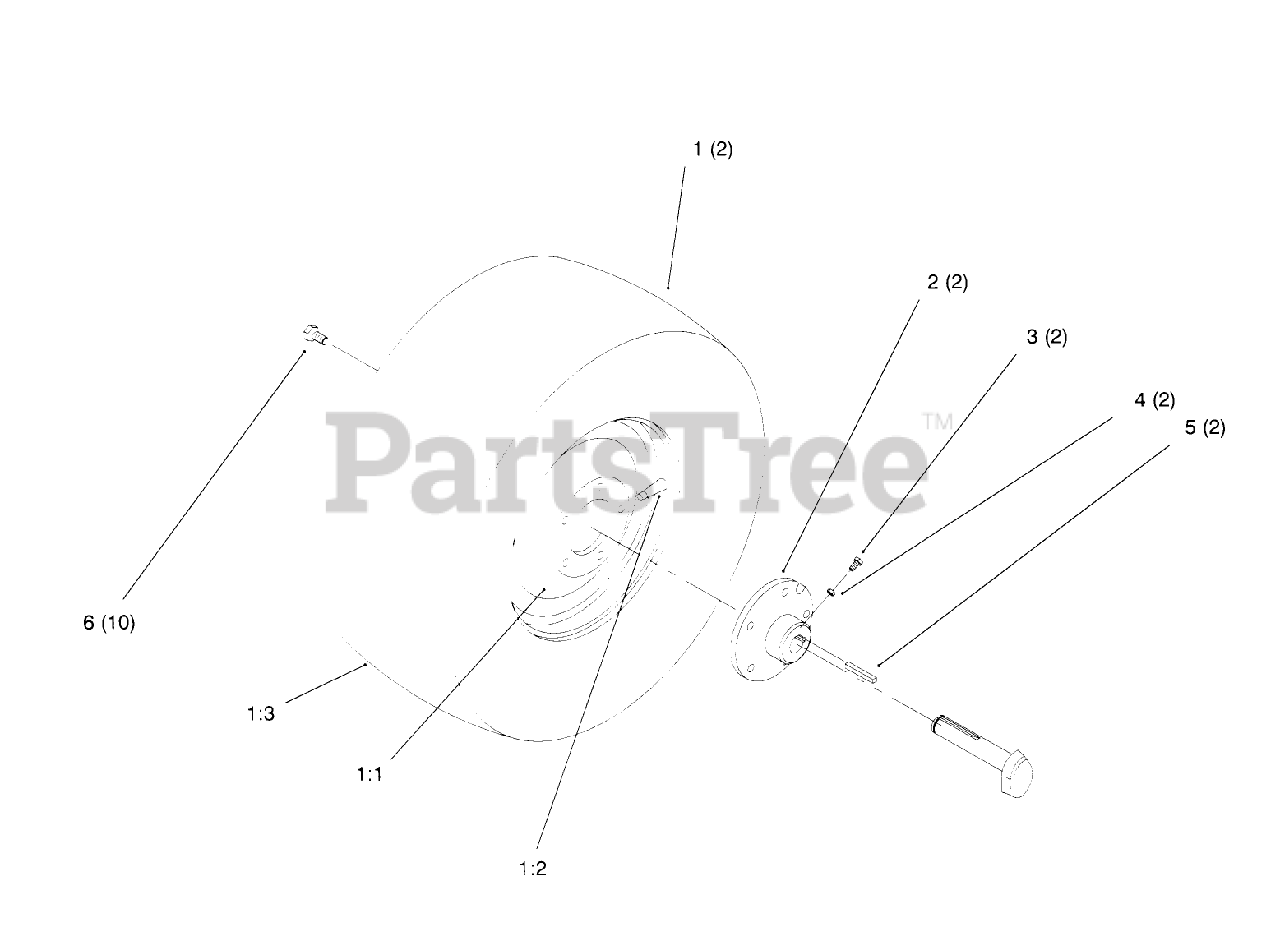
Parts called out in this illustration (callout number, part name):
1:1	WHEEL
1:2	VALVE
2	HUB-WHEEL
3	SCREW-SET, SQH
4	NUT-JAM
5	KEY-SQUARE
6	BOLT-LUG
